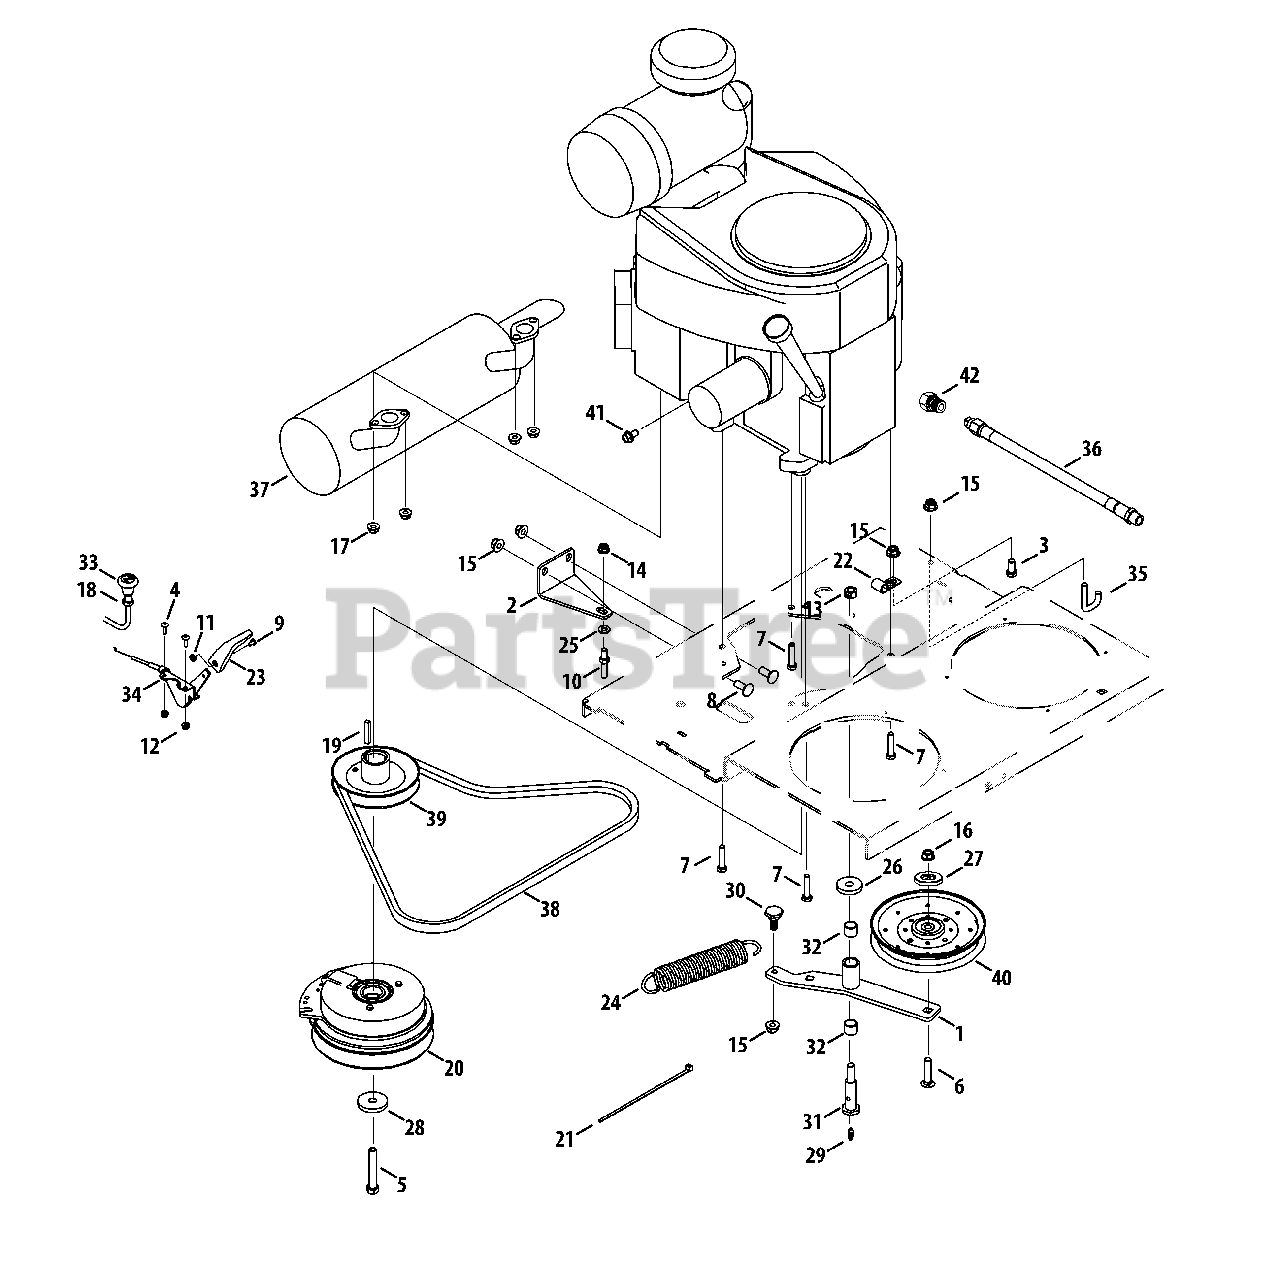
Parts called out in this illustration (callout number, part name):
1	Idler Bracket
2	Clutch Retainer Bracket
3	Hex Cap Screw, 3/8-16 x .75
4	Screw, #10-24 x .625
5	Hex Cap Screw, 7/16-20 x 2.75
6	Carriage Bolt, 3/8-16 x 1.00
7	Hex Cap Screw, 3/8-16 x 1.25
8	Carriage Bolt, 3/8-16 x 1.00
9	Screw, #8-32 x .375
10	Stud, Pivot Ball Joint
11	Nut, #8-32, Hex
12	Nut, #10-24, Hexlock
13	Nut, 7/16-14, Hexlock
14	Nut, 5/16-18, Flangelock
15	Nut, 3/8-16, Flangelock
16	Nut, 3/8-16, Flangelock
17	Nut, M8-1.25, Hexlock
18	Jam Nut, 3/8-24
19	Key, 1/4 x 1.50
20	Electric PTO Clutch
21	Cable Tie
22	Clip, .407 x 1.80
23	Throttle Control Knob
24	Extension Spring, 1.5 x 7.5
25	Washer, .344 x .688 x .065
26	Washer, .471 x 1.50 x .225
27	Pulley Cap
28	Washer, .471 x 1.50 x .225
29	Grease Fitting
30	Shoulder Screw, .625 x .302, 3/8-16
31	Shoulder Bolt, .625 x 1.947, 7/16-14
32	bearing, .638 x .753 x .615
33	Choke Control Cable
34	Throttle Cable
35	Transmission Spring Hook
36	Oil Drain Hose
37	Muffler
39	Drive Pulley
40	Idler Pulley
41	Hex Cap Screw, M8 x 1.25 x 16MM
42	Hex Fitting, 1.0
